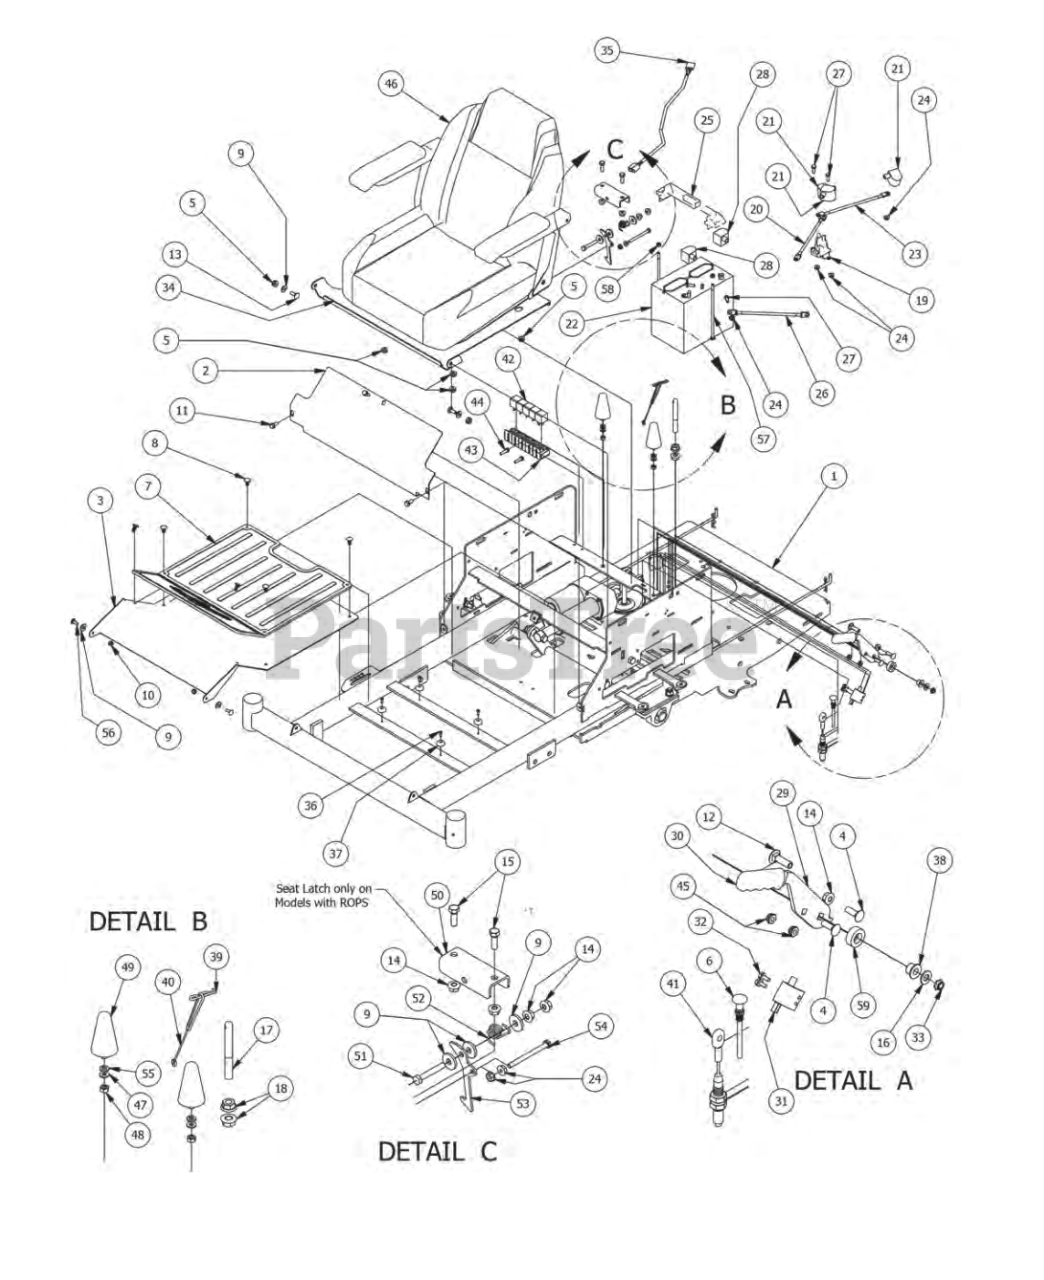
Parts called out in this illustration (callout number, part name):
1	ZT/CZT Frame 2013 Models
2	2013 ZT/CZT Cooler Cover
3	ZT/CZT FLOOR PANEL
4	5/16" x 1" Carriage Bolt
5	5/16-18 Nylon Flange Nut
7	Zt Floorboard Mat
8	Ratchet Fastener
9	360 ID Plastic Washer
10	1/4" Nylock Nut
11	5/16 x 3/4 washer head type F screw
12	3/8" x 1 1/4" Carriage Bolt
13	5/16" x 7/8" Carriage Bolt
14	5/16" Flange Nut
15	5/16" x 1" Bolt
16	3/8" Flat Washer
17	Seat Braket Pin
18	1/2" Flange Nut
20	24 in red battery cable
23	12 in red battery cable
24	1/4-20 Hex Flange Nuts Zinc w/Serrations
25	Battery Hold Down
26	Starter to chassis cable
27	1/4-20 x 3/4 GR 5 Hex Bolts Zinc
28	Black Boot For ground cable
29	Brake Handle Cam Over
30	Rubber Brake Grip-cZT/ZT 2013
31	Safety Switch
32	12-24x 1/2 HWH Bolt
33	3/8 Nylock Jam Nut 1/2 Nut
34	2013 ZT Seat Plate
35	Seat Switch Adapter
36	# 10 x 1/2" Self Taping Screw
37	Button Bumper
38	Bronze Bushing SF-1220-8
39	Seat latch pin
40	seat pin lanyard
41	Brake Cable
42	Relay Terminal
43	Harness-ZT Only 2008 and up
44	1/4 x 1 Hex Head tek screw
45	5/16-18 Nylock Jam Nut 1/2 Nut
46	2013 ZT Seat
47	1/4" Flat Washer
49	Rubber Cone-1621-153
50	ZT/CZT Seat Latch Bracket
51	5/16-18 X 2 Hex C/S (GR.5) ZC
52	Torsion Spring for Seat latch
53	Seat Latch Lever
54	1/4 x 3 Hex Bolt - Grade 8- ACS
55	5/16" Lock Washer
56	1/4" x 3/4" Carriage Bolt
57	1/4-20 X 8 Carriage Bolt
58	1/4-20 Hex Nut
59	2015 Brake Lever Spacer
